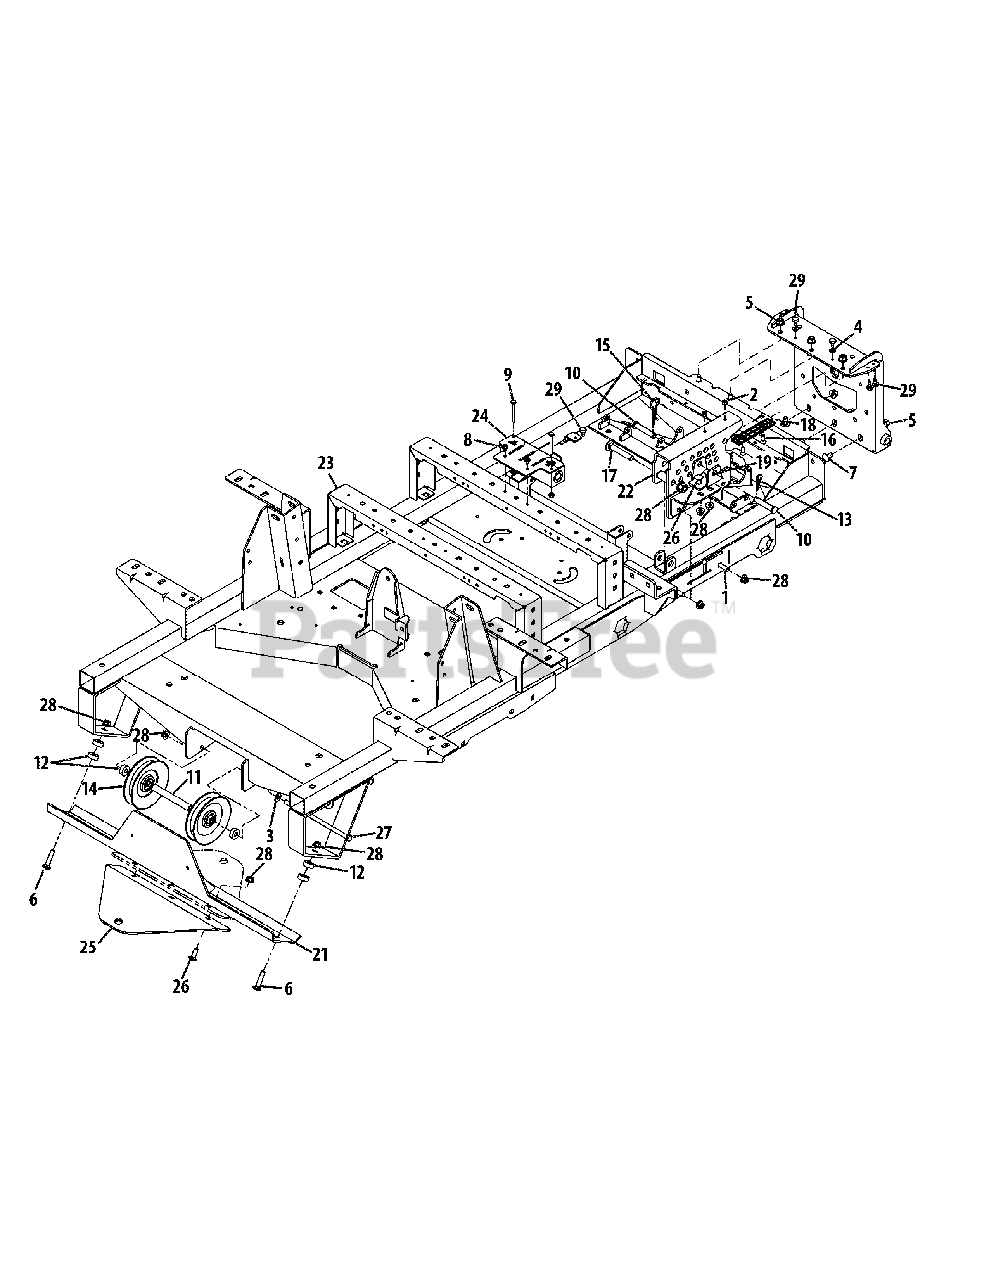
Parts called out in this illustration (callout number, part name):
1	Carriage Bolt, 3/8-16 x 1.25
2	Nut, 1/4-20
3	Washer, .406 x .813 x .063
4	Washer, .344 x .688 x .063
5	Flange Counter Lock Nut, 3/8-16
6	Carriage Bolt, 3/8-18 x 1.75
7	Carriage Bolt, 3/8-16 x .75
8	Hex Flange Screw, 1/4-20 x .500
9	Hex Screw, 1/4-20 x 2.25
10	Clevis Pin, 1/2 x 2.500
11	Spacer, .385 x .750 x 4.89
12	Spacer, .406 x 1.00 x .38
13	Hair Pin, 1/2 x 1.625 x .125
14	Idler Pulley
15	Hitch Pin, .120 x 3.00
16	Flat Head Screw, 1/4-20 x .750
17	Carriage Bolt, 1/2-13 x 3.00
18	Wear Plate, 1.125 x 5.0
19	Cylinder Mount Bracket
20	Front Axle Bracket Assembly
21	Inner Guards Bracket Assembly
22	Lift Index Housing Assembly
24	Manifold Mount Bracket
25	Hitch Bracket
26	Carriage Bolt, 3/8-16 x 1.00
27	Hex Screw, 3/8-16 x 8.50
28	Flange Lock Nut, 3/8-16
29	Rubber Bumper, .62 x .22
